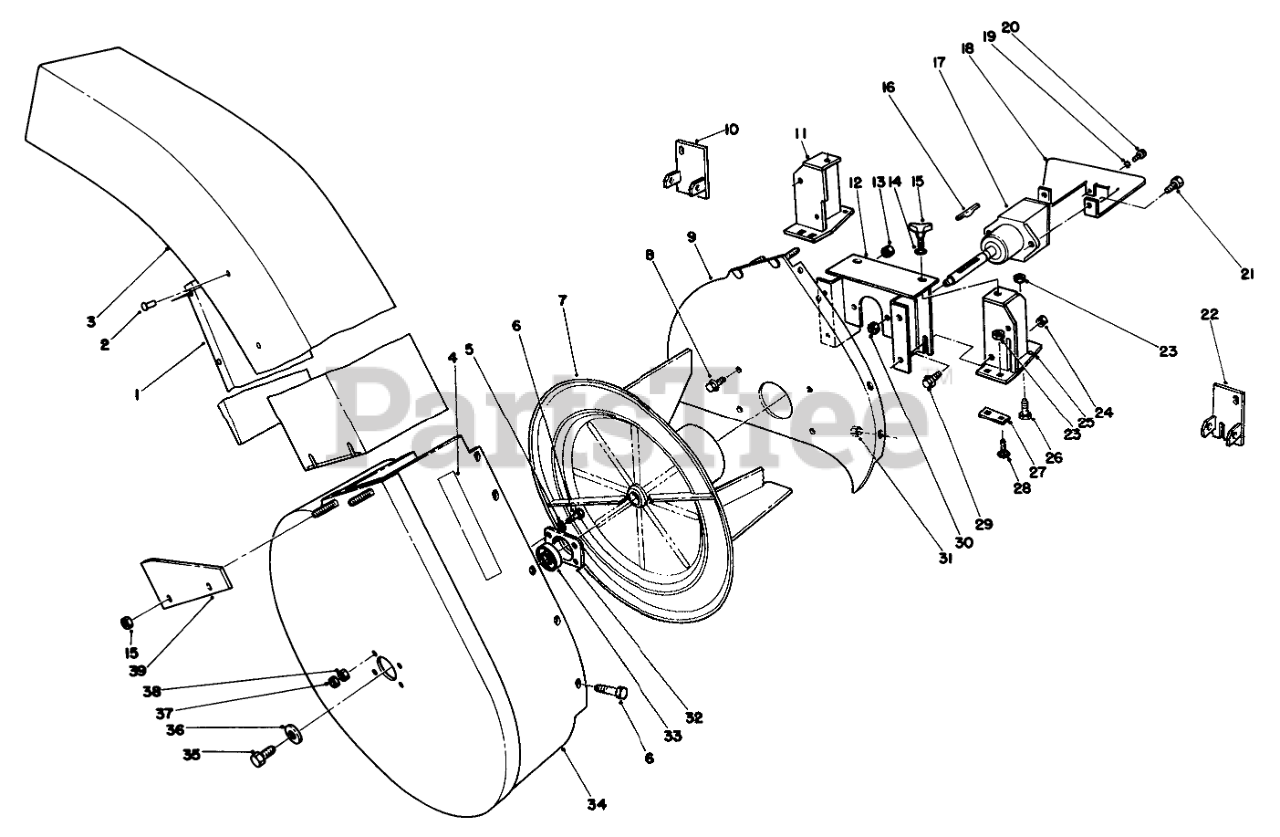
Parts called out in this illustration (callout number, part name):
1	Deflector-Chute
3	Chute Assembly (Incl. Ref. #1 & 2)
4	Decal-Waming
5	WASHER-LOCK
6	SCREW-HH
7	Impeller
8	SCREW-HHF
9	Mounting Plate
10	Bracket-Deflector L.H.
11	LH BRACKET ASM
12	Blower Mount
13	NUT-LOCK, NI
14	WASHER-FLAT
15	Knob
17	Asm-Gear Box
18	Cover-Gear Box
19	WASHER-LOCK, EXT
21	SCREW-HH
22	Bracket-Deflector R.H.
23	NUT-LOCK, CONE
24	NUT-JAM
25	RH BRACKET ASM
26	SCREW-HH
27	Plate-Bracket
28	BOLT-CARR
29	SCREW-HHF
30	NUT-LOCK, NI
31	NUT-LOCK, NI
32	CUP-BEARING
33	BEARING-BALL
34	Blower Housing
35	CAPSCREW 3/8 16 3/4
36	SPACER
37	NUT-JAM
38	NUT-HEX
39	Bracket
